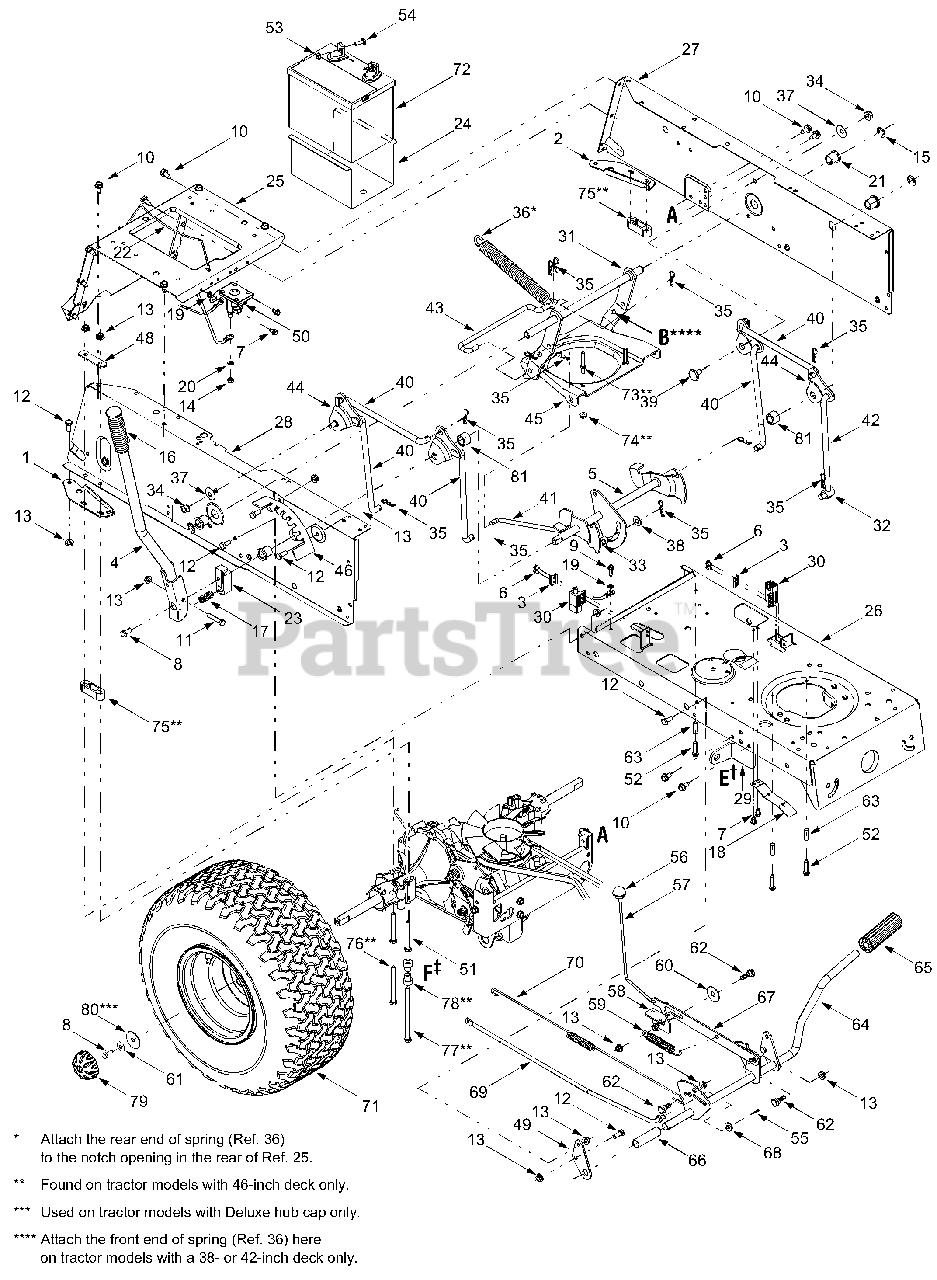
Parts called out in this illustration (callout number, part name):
6	Self-tapping Screw, #10-16 x .5
7	Self-tapping Screw, 1/4-20 x .5
8	Hex Cap Screw, 5/16-24 x .75
9	Self-tapping Screw, 1/4-20 x .75
10	Self-tapping Screw, 5/16-12 x .75
11	Hex Cap Screw, 5/16-18 x 1.5
12	Hex Screw, 5/16-18 x .75
13	Lock Nut, 5/16-18
14	Hex Nut, 1/4-20
15	E-Ring, .625 Dia Shaft
16	Handle Grip
17	Compression Spring, .55 x 1.37
18	Switch Actuator Spring
19	External Lock Washer, 1/4
20	Lock Washer, 1/4
21	Flange Bearing, .632 ID
22	Battery Hold-down Rod
23	Lift Shaft Connector
33	Ferrule, 3/8-24 x .375
34	Flange Lock Nut, 3/8-16
35	Internal Cotter Pin, .080 x 1.56
36	Extension Spring, .730 x 13.0
37	Bell Washer, .389 x 1.12 x .030
38	Flat Washer, .385 x .87 x .060
39	Shoulder Bolt, .625 x .217
40	Deck Hanger Link
41	Deck Disengagement Rod
42	Deck Hanger Link
43	Stabilizer Rod
44	Lift Link
46	Deck Lift Index Bracket
51	Hex Cap Screw, 5/16-18 x 2.75
52	Self-tapping Screw, 1/4-20 x 1.25
53	Hex Sems Nut, 1/4-20
54	Hex Screw,1/4-20 x .75
55	Cotter Pin, 1.0
56	Ball Knob
57	Brake Lockout Rod
58	Bracket
59	Extension Spring, 4.31
60	Flat Washer, .442 x 1.38 x .060
61	Bell Washer, .34 x .872 x .060
62	Shoulder Screw, .437 x .286
63	Spacer, .260 x .372 x 1.030
66	Spacer, .640 x .76 x 2.63
67	Brake Lockout Bracket
68	Flat Washer, .344 x .750 x .120
69	Brake Rod
70	Extension Spring, 22.16
72	Battery, 270 CCA
73	Flange Lock Nut, 1/4-20
74	Belt Guard Pin, 1/4-20
75	Spacer
76	Hex Cap Screw, 5/16-18 x 3.25
77	Hex Cap Screw, 5/16-18 x 5.25
78	Shoulder Spacer
79	Deluxe Hub Cap
80	Flat Washer, .350 x 1.59 x .062
81	Spacer, .635 x 1.0 x .696
